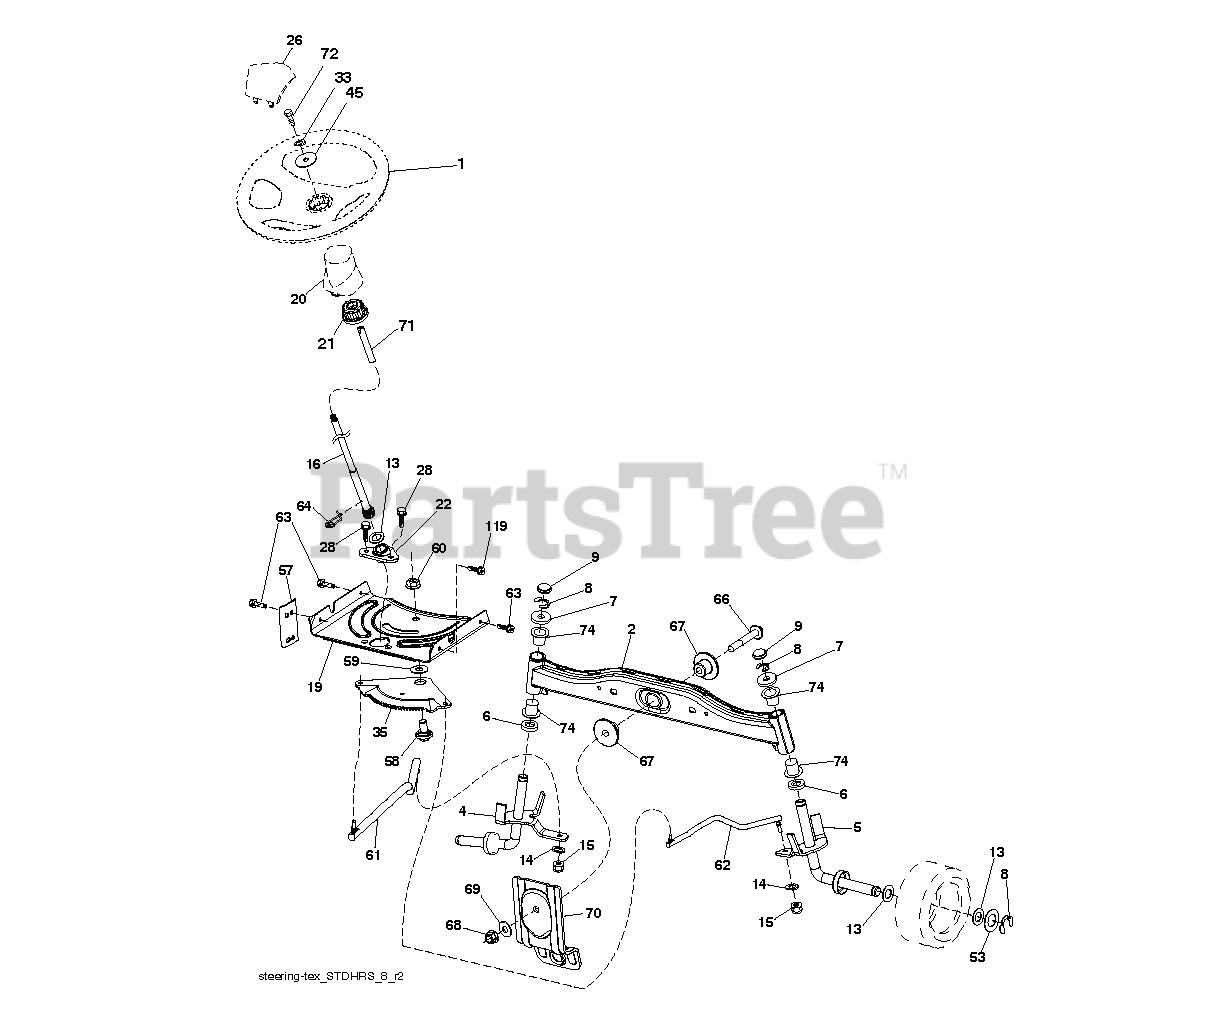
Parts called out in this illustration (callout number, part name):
1	WHEEL.STEER.HUSQ.SR.498.OVMLD
2	AXLE HALF ASM-WELDED
4	SPINDLE.STEERING.ASM.LH.13".TI
5	SPINDLE.STEERING.ASM.RH.13".TI
6	THRUST WASHER
9	CAP.SPINDLE.BLACK
14	WASHER, LOCK 3/8
15	NUT CROWNLOCK 3/8-24
16	SHAFT.STEER.3/4.PLATED.TEX
19	PLATE.STEER.DDL.NLT/NG
20	STEERING.BOOT.HUSQ.LT
21	ADAPTER, WHEEL STNG..
22	STEERING.SUPT.LOWER.
26	INSERT.CAP.WHL.STRG.HUSQ.PREM
28	SCREW, 3/8-16X3/4
33	LOCKWASHER
35	GEAR.SECTOR.PLATE.DDL.
45	WASHER.11/32
53	WASHER.HARDENED
57	BRACKET.UPSTOP.TEX
58	BOLT.SHOULDER.SECTOR.P
59	WASHER.THURST.SECTOR.S
60	NUT FLANGE LOCK 5/8-11
61	DRAGLINK.LH.BALLSTUD.D
62	DRAGLINK.RH.BALLSTUD.D
63	SCREW
64	RETAINER.CLIP.SPRING.S
66	BOLT HEX FGHD 7/16-14 X 3 SERR
67	BUSHING.PM.FRONT AXLE
68	NUT.LOCK.FLANGE.7/16
69	WASHER.1.5X.505X.118
70	BRACKET.SUSP.MWR.FRT.30"SRD
71	SHAFT.EXTEN.STRG.SPLINE
72	BOLT 5/16-18 X 4 W/PATCH
74	BRNG T
119	SHOULDER BOLT 5/16-18TT
